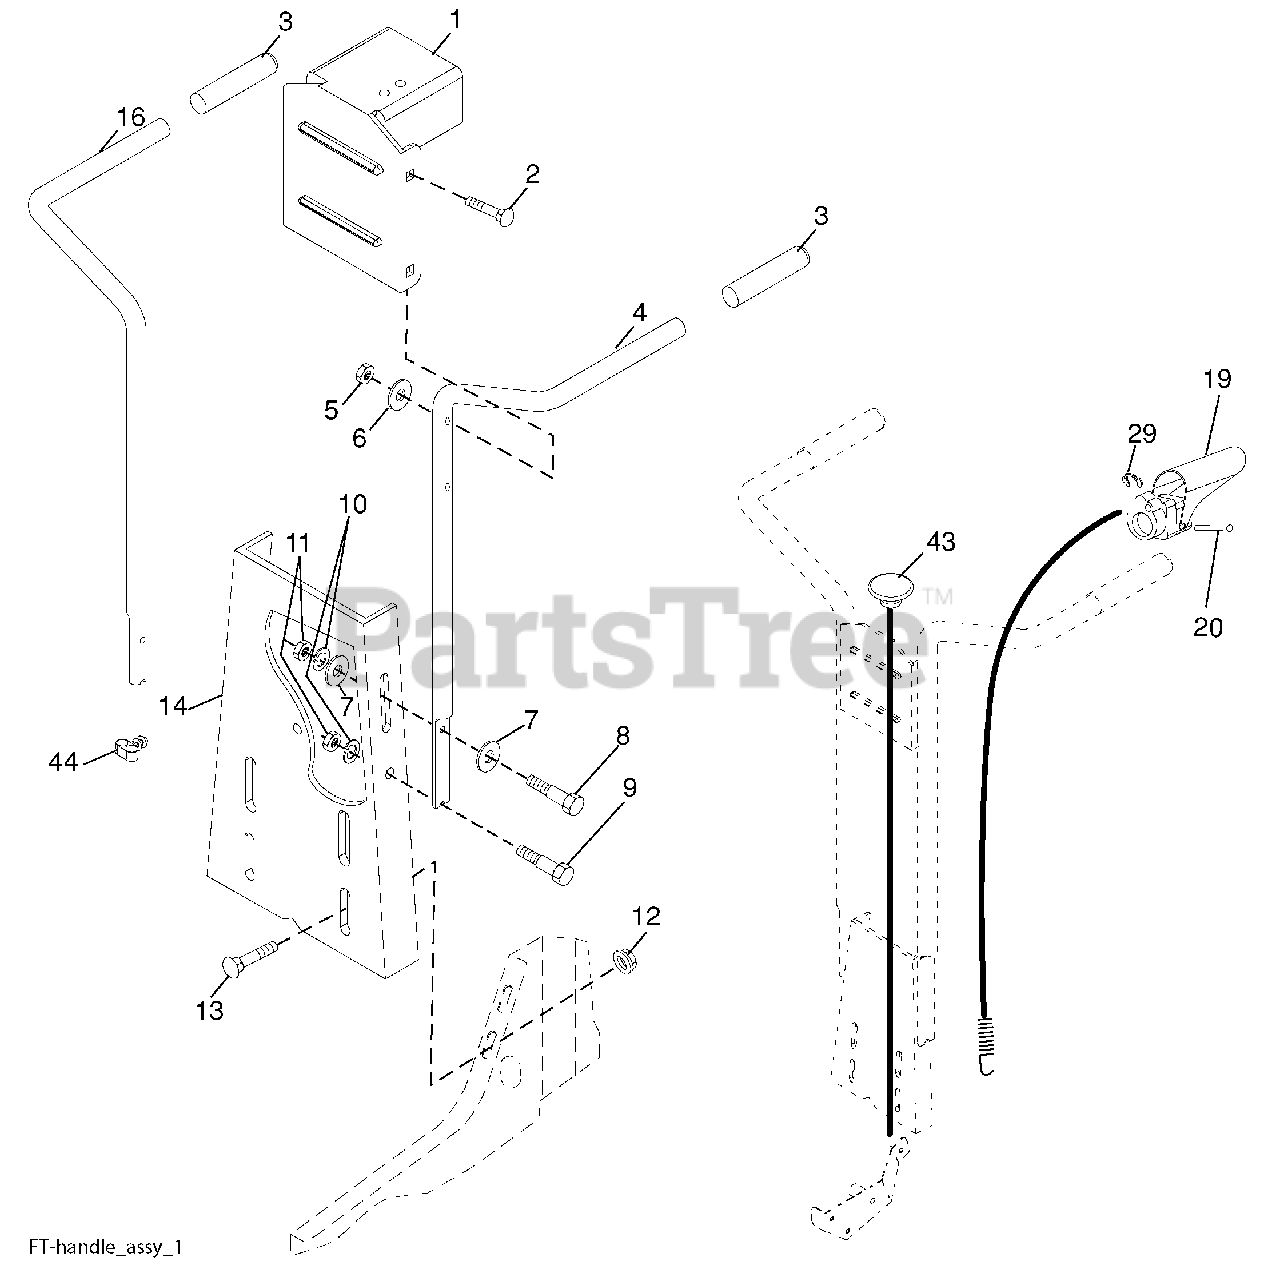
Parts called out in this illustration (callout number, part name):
1	Bracket, Handle
2	Bolt, Carriage 5/16-18 x 1-1/2
3	Grip, Handle
4	Handle, L.H.
5	Nut, Hex, Crownlock 5/16-18
6	Washer 11/32 x 11/16 x 16 Ga.
7	Washer 3/8 x 7/8 x 14 Ga.
8	Bolt, Hex Head 5/16-18 x 1-1/4
9	Bolt, Hex Head 5/16-18 x 1
10	Washer, Lock 5/16
11	Nut, Hex 5/16-18
12	Nut, Hex, Flanged 5/16-18
13	Bolt, Carriage, Gr. 5 5/16-18 x 3/4
14	Panel, Handle
16	Handle, R.H.
19	Tine Control Lever Assembly
20	Pin, Pivot
29	Retaining Ring
43	Cable Assembly, Reverse
44	Clip
